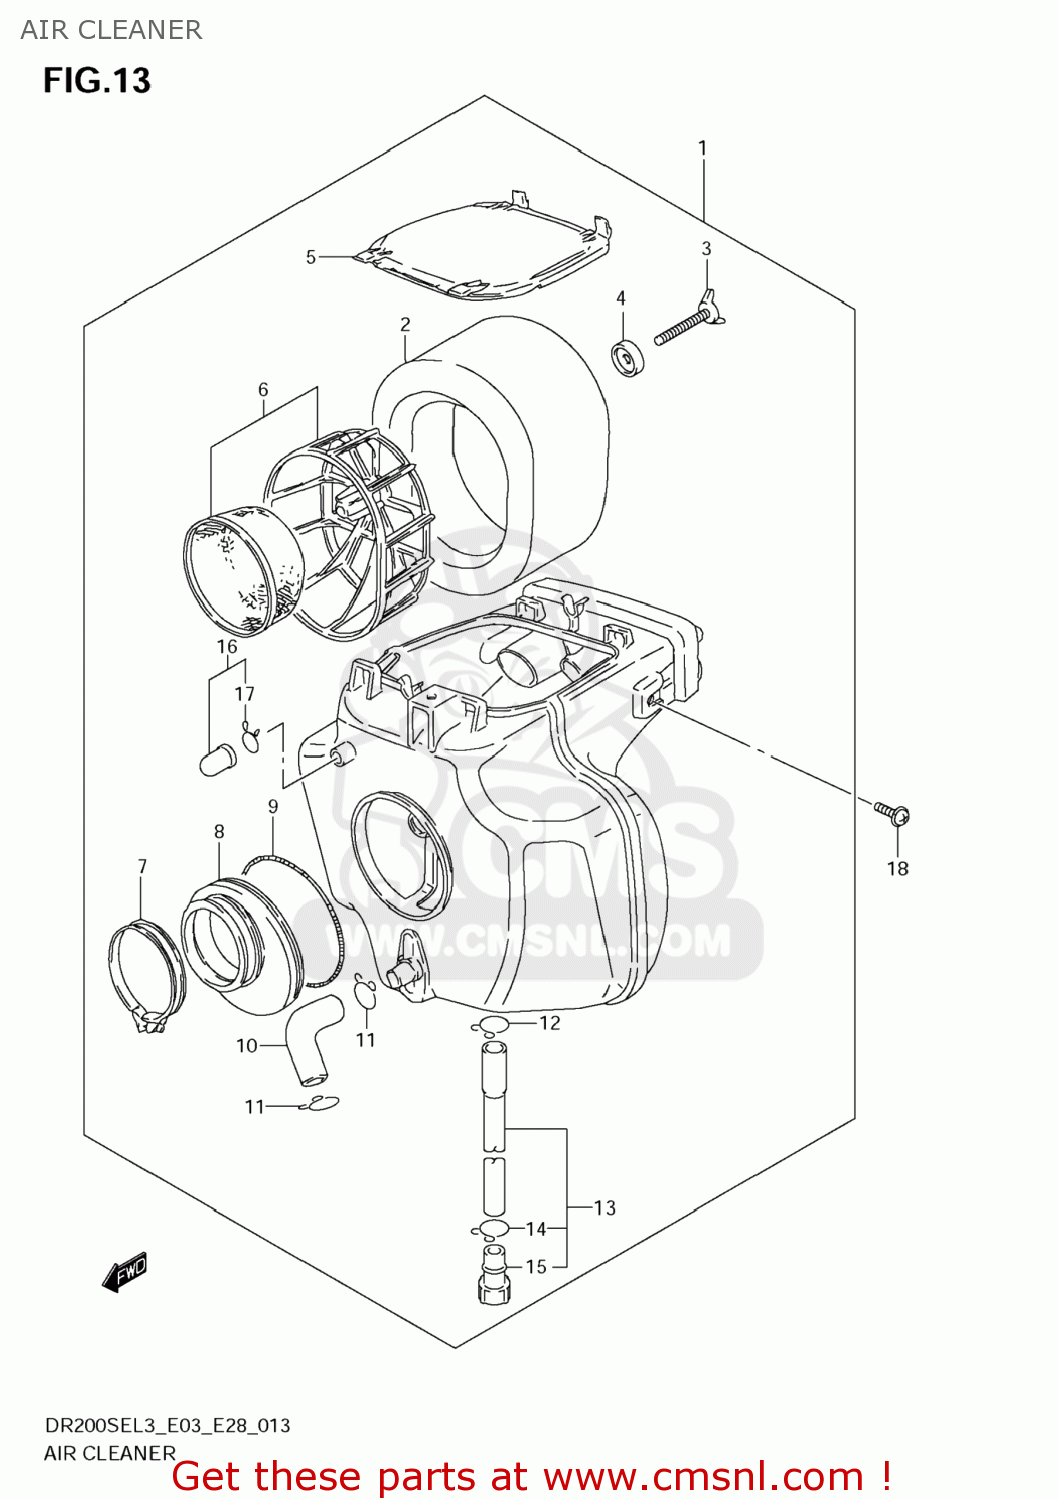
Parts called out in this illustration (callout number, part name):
1	CLEANER ASSY,AIR
2	FILTER
3	BOLT,WING
4	WASHER,FILTER HOLDER
5	CAP
6	HOLDER
7	CLAMP
8	TUBE,AIR CLEANER OUTLET
9	CLAMP,AIR CLEANER SIDE
10	TUBE,BREATHER
11	CLIP
12	CLIP
13	TUBE,DRAIN
14	CLIP
15	STOPPER,DRAIN
16	PLUG,DRAIN
17	CLIP
18	SCREW
